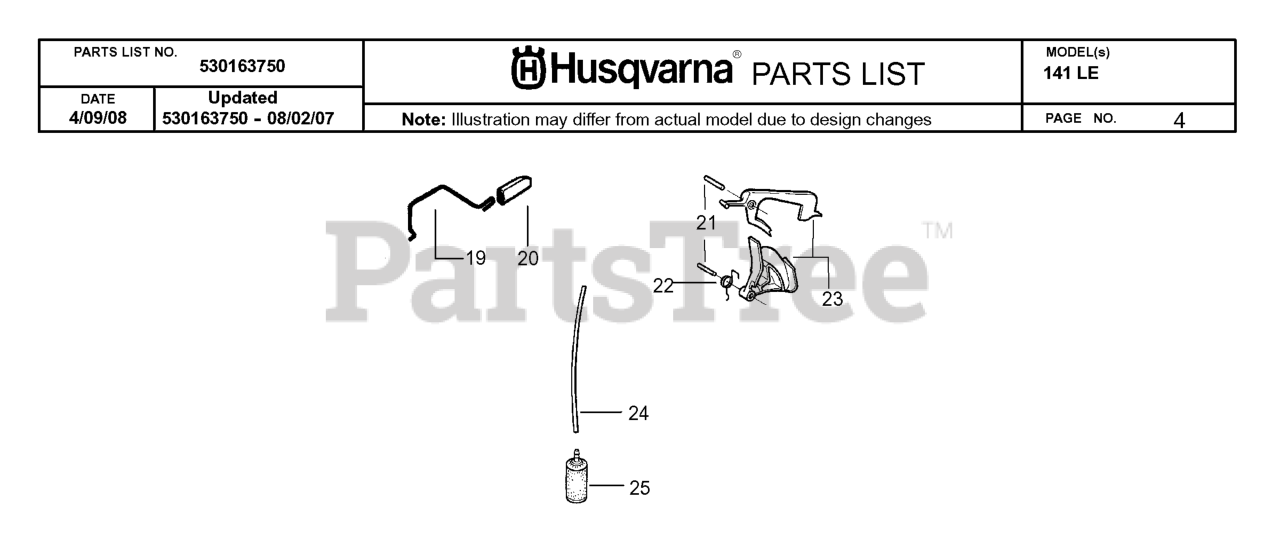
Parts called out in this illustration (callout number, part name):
19	THROTTLE SHAFT 36/41
20	THROTTLE ACTUATOR 36/41
21	PIN,TRIGGER 36/41
22	TRIGGER SPRING 36/41
23	THROTTLE TRIGGER-KIT
24	HOSE. FUEL
25	FUEL PICK-UP
